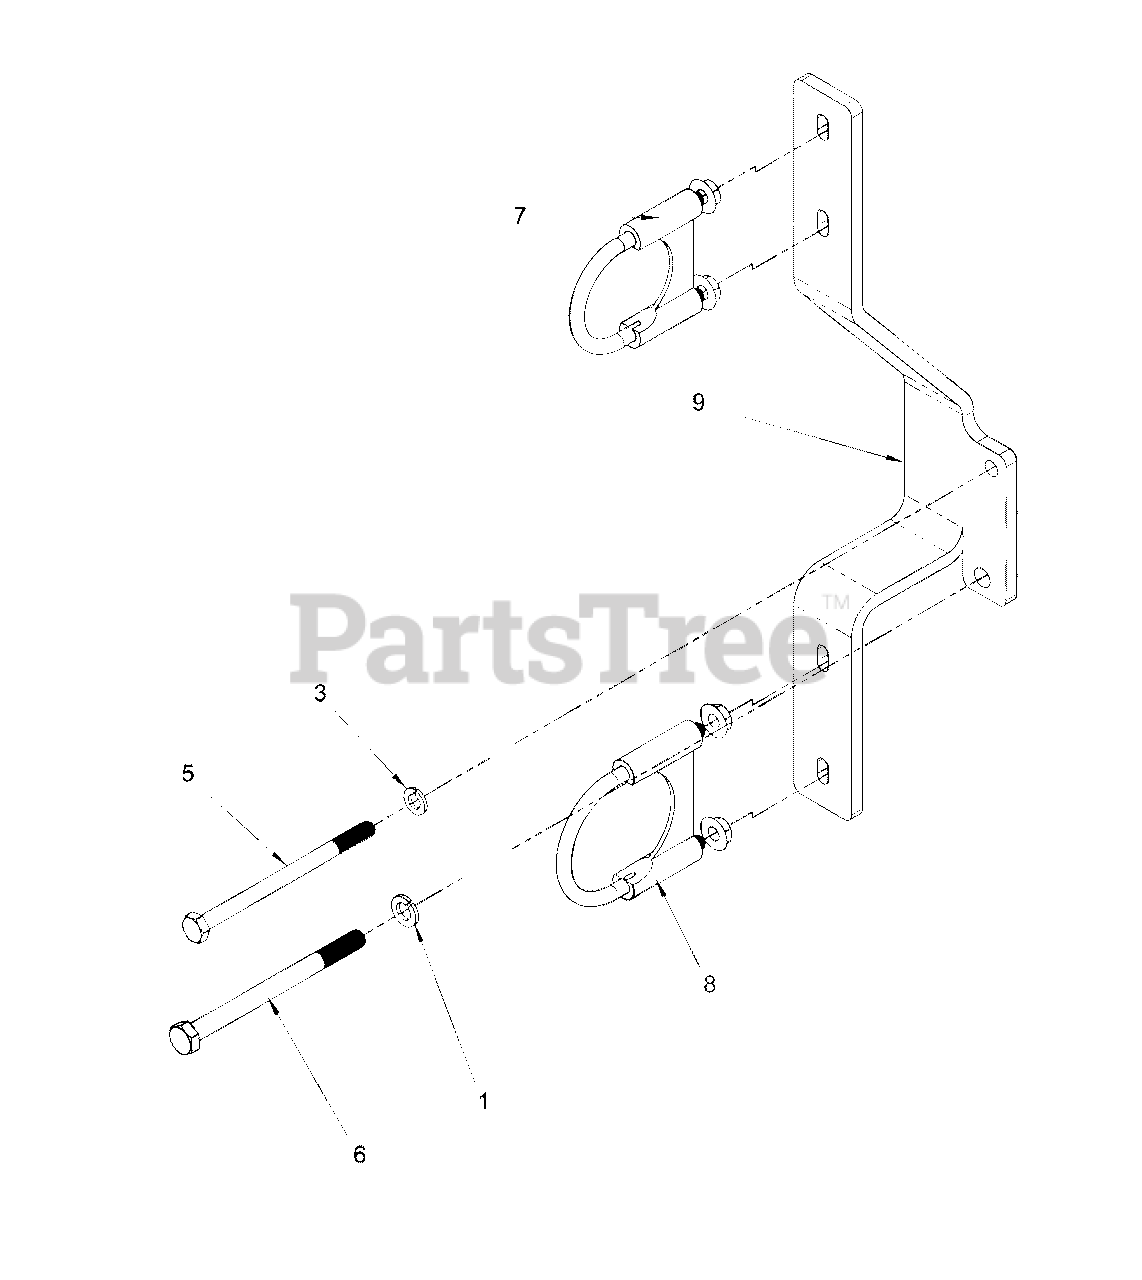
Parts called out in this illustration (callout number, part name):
1	* WASHER
3	* WASHER
5	* BOLT
6	* BOLT
7	* CLAMP
8	* U-BOLT
9	* BRACKET
